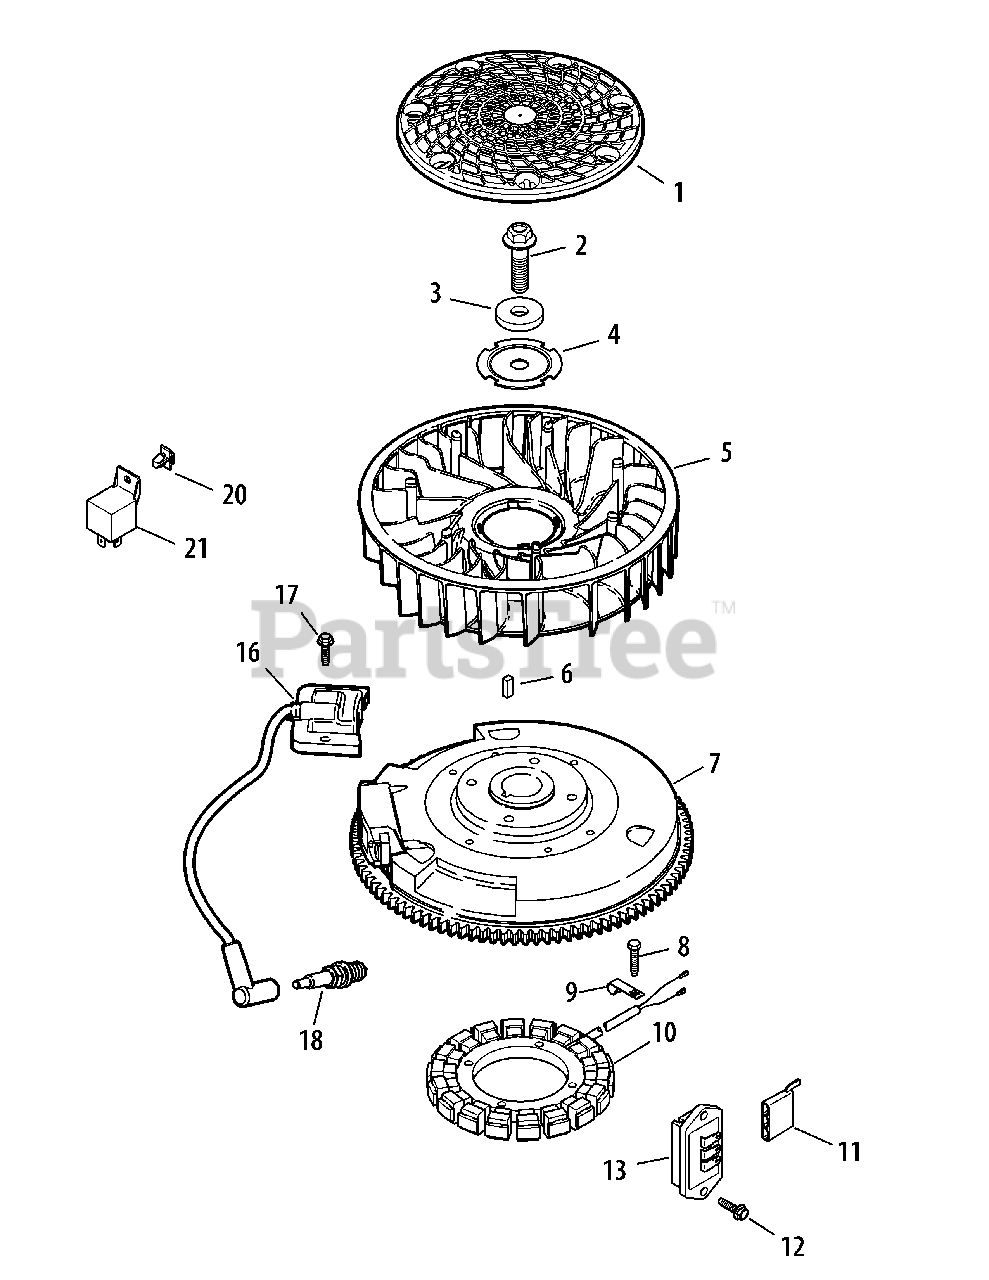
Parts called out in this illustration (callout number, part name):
2	Hex Flange Screw
4	Fan Mounting Plate
6	Straight Flywheel Key
7	Flywheel
8	Thd. Frm. Screw, M5 X 0.8 X 25
10	15 Amp Stator Kit
12	Flg. Thd. Frm. Screw, M5 X .8 X 20
13	Regulator/Rectifier
16	Ignition Module (CDI Fixed)
17	Flg. Thd. Frm., M5 X .8 X 20
18	Spark Plug (Std)
20	Not used in this application
21	Not used in this application
